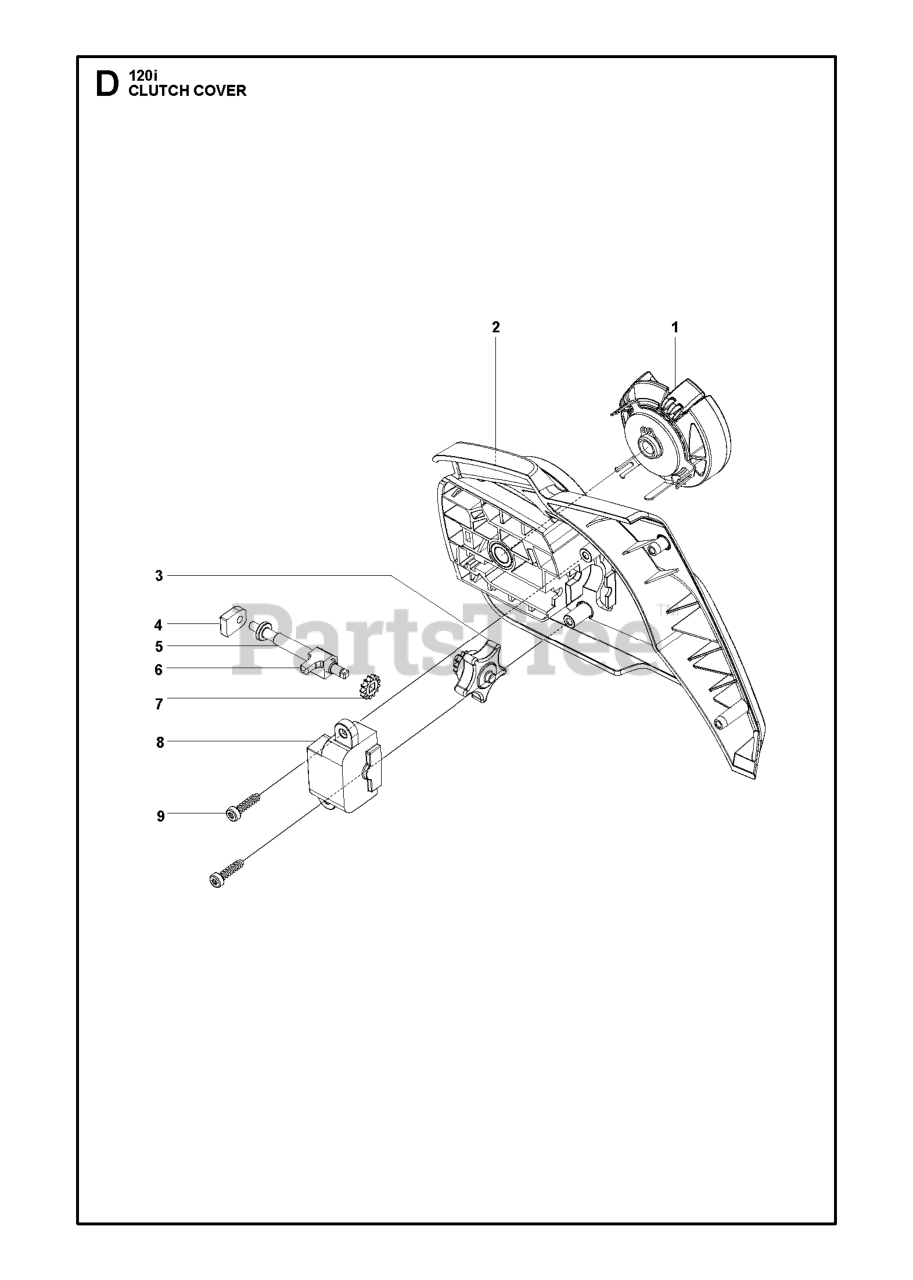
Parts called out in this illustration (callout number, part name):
2	CLUTCH COVER
3	CHAIN TENSIONER
5	SHAFT TENSION
6	PLATE ADJUSTMENT
7	PINION ADJUSTMENT
8	COVER PINION
9	SCREW ST4X12
